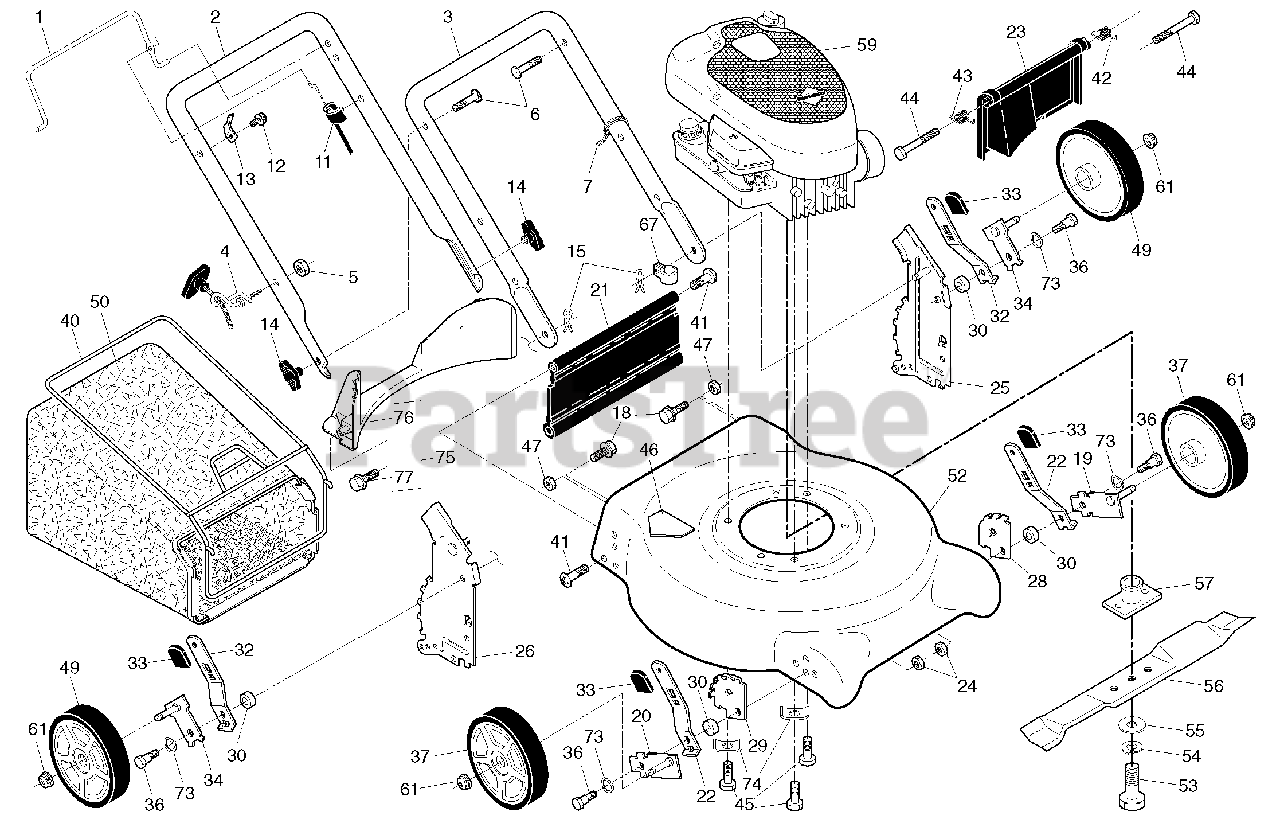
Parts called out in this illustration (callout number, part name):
1	Control Bar
2	Upper Handle
3	Lower Handle
4	Rope Guide
6	Handle Bolt
7	Wire Tie
11	Cable, Engine Zone Control
12	Hex Washer Head Screw
13	Up-Stop Bracket
14	Knob, Handle
15	Hairpin Cotter
18	Screw
19	Axle Arm Assembly, Front, LH
20	Axle Arm Assembly, Front, RH
21	Kit, Rear Skirt
22	Selector Spring, Front
23	Rear Door Assembly
24	Nut, Hex 5/16-18
25	Handle Bracket Assembly, LH
26	Handle Bracket Assembly, RH
28	Wheel Adjusting Bracket, Front, LH
29	Wheel Adjusting Bracket, Front, RH
30	Spacer
32	Selector Spring, Rear
33	Selector Knob
34	Axle Arm Assembly, Rear, LH
36	Shoulder Bolt 5/16-18
37	Wheel & Tire Assembly, Front 7 x 1-3/4
40	Frame, Grassbag
41	Hinge Screw
42	Spring, Rear Door, LH
43	Spring, Rear Door, RH
44	Bolt, Rear Door
45	Hex Head Thread Rolling Screw 3/8-16 x 1
46	Danger Decal
47	Nut, Hex
49	Wheel & Tire Assembly, Rear 8 x 1-3/4
52	Kit, Mower Housing
53	Hex Head Screw 3/8-24 x 1-3/8 Grade 8
54	Helical Lockwasher
55	Hardened Washer
56	21" Blade
57	Blade Adapter
61	Flanged Locknut, Hex
67	Clip, Cable
73	Washer, Curved, Cylindrical
74	Washer, Special, Engine
75	Kit, Rear Baffle
76	Baffle, Rear
77	Screw, Rear Baffle
77	Operator's Manual, English
77	Operator's Manual, French
77	Repair Parts Manual, English
